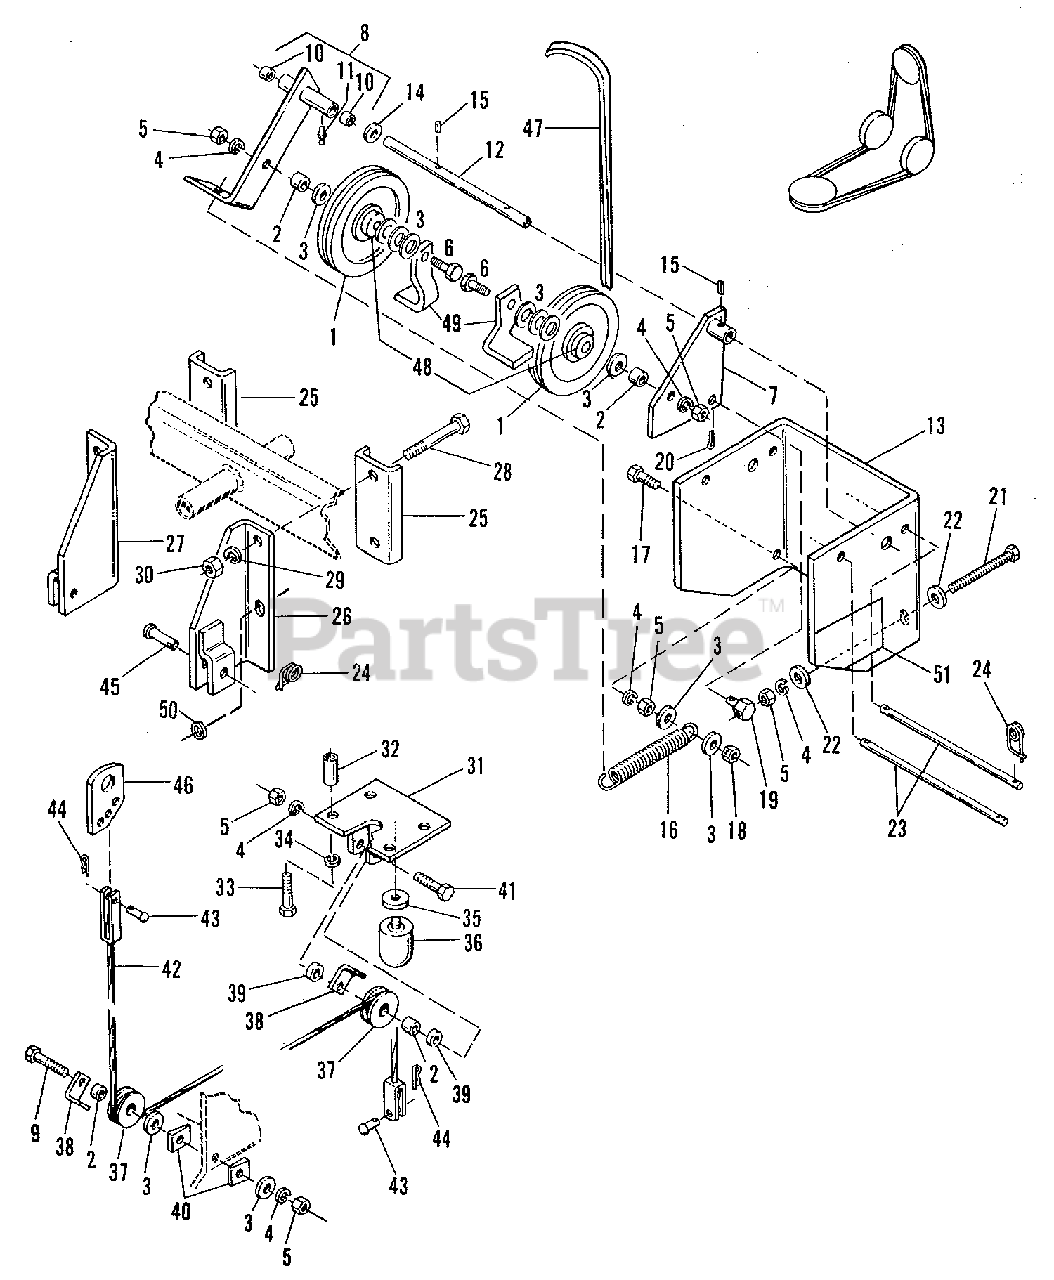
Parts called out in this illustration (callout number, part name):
1	PULLEY ASSEMBLY
1	RING, Retaining
3	WASHER, Plain, 3/8
4	LOCKWASHER, 3/8
6	CAPSCREW, Hex Head, 3/8NC x 2-1/4
7	ARM SUPPORT ASSEMBLY
8	ARM ASSEMBLY
9	CAPSCREW, Hex Head, 3/8NC x 2-1/4
11	FITTING, Lube, 1/4
12	SHAFT, Idler Support
13	SUPPORT, Idler
14	WASHER, Plain
15	PIN, Spring, 3/16
17	CAPSCREW, Hex Head, 3/8NC x 1-1/4, Full Thread
18	NUT, Hex, Lock, 3/8NC
20	PIN, Cotter, 3/32 x 1
21	CAPSCREW, Hex Head, 3/8NC x 4-1/4
22	WASHER, Plain, 13/32 x 1-1/2 x 11 Ga.
24	CLIP, Safety Pin
25	BRACKET, Hitch
26	HITCH ASSEMBLY, Mower, R.H.
27	HITCH ASSEMBLY, Mower, L.H.
28	CAPSCREW, Hex Head, 1/2NC x 5, Gr. 8
28	CAPSCREW, 1/2NC x 4, Gr. 8
29	LOCKWASHER, 1/2
31	SUPPORT, Plate Assembly
33	CAPSCREW, Hex Head, M8 x 60MM
34	LOCKWASHER, 5/16
35	WASHER, Special
36	STOP, Rubber
38	GUARD, Cable
39	WASHER, Special
40	WASHER, Special
41	CAPSCREW, 3/8NC x 1-3/4, Gr. 8
42	CABLE, Mower Lift
44	CLIP, Hairpin
49	STOP, Lock
50	WASHER, Plain, USS 1/2
51	DECAL, Adjustment
52	DECAL, Caution
